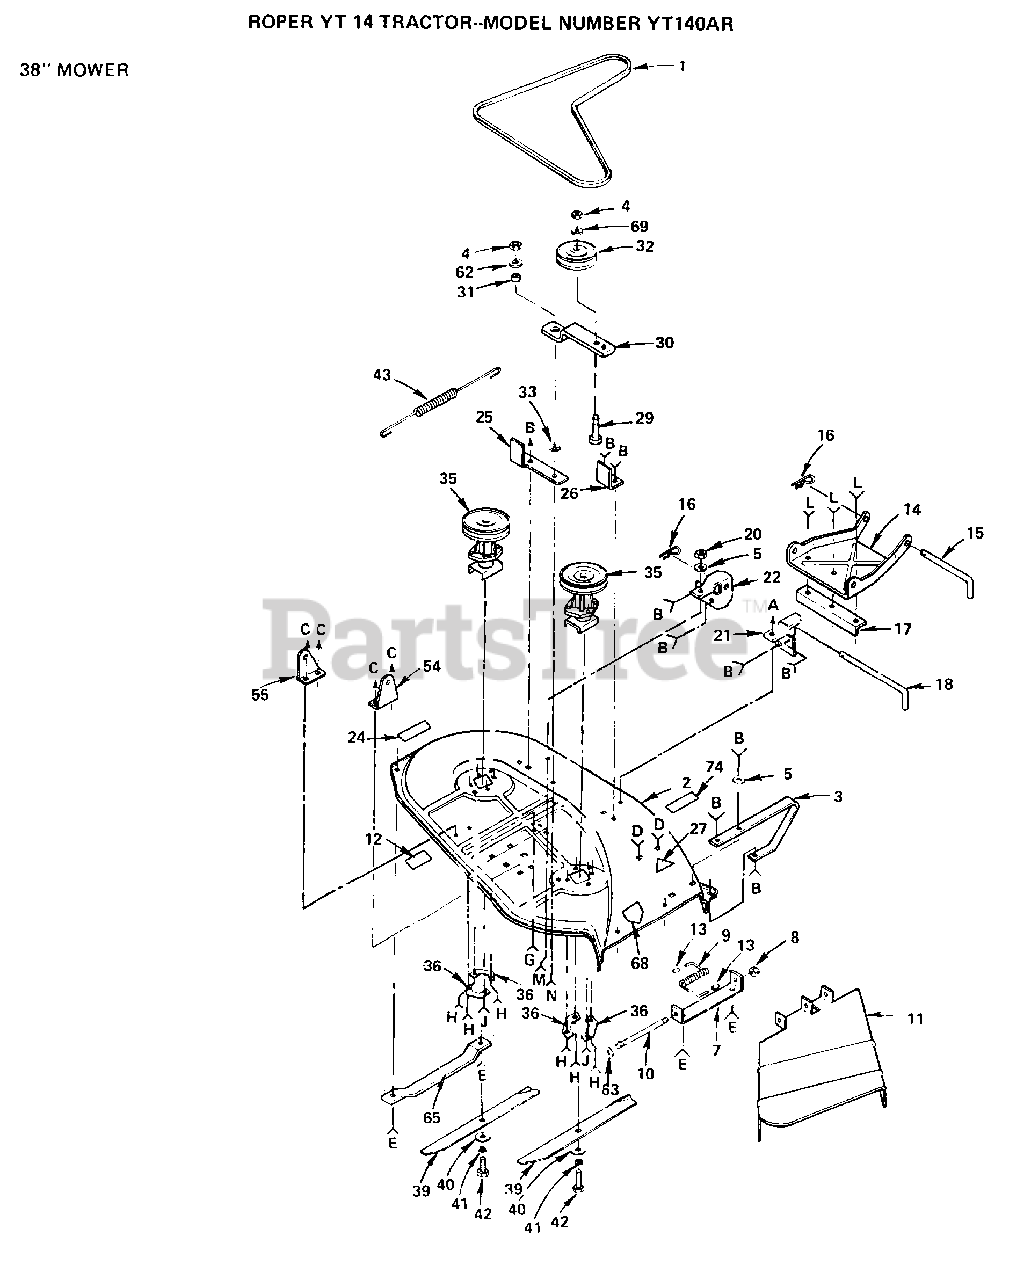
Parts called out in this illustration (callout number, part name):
1	BELT-V.79.1.MWR
5	WASHER M
10	ROD-HINGE T
11	DEFLECTOR-SHLD T
13	CAP-SLEEVE LT
14	LINK.PARALLEL
15	"ROD, FRT. PARAL T"
16	RETAINER.SPRING
17	LINK STOP
24	DECAL INSTRUCTION CAUTION
27	DECAL - SAFETY STANDARD
31	SPACER RETAINER
32	IDLER-FLAT T
33	"WASHER, WEAR LT"
36	SUPPORT PLATE LT
40	WASHER
41	LOCKWASHER
42	BOLT.3/8-24X1-1/2
43	"SPRING.EXT.8.5"""
54	"BRKT,SUSP RH T"
55	"BRKT,SUSP REAR LH"
63	WASHER
65	RUNNER-LH M
74	DECAL.WARNING.T
